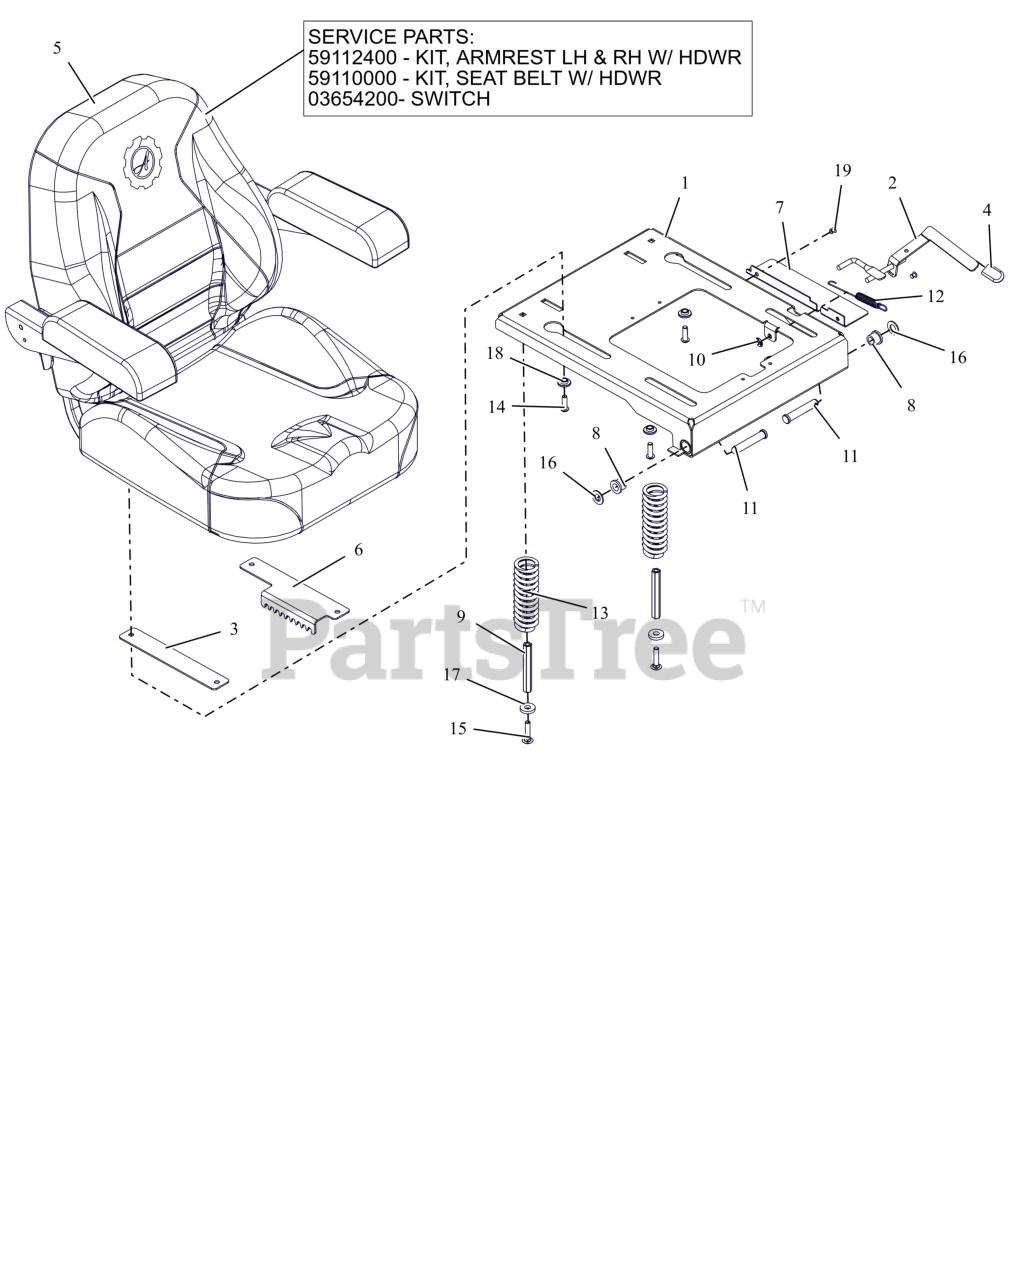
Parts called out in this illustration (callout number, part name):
1	WLDMT, SEAT PLATE HD
2	WLDMT, SEAT SLIDE LEVER
3	PLATE, ADJUSTABLE SEAT SLIDE
4	GRIP, SEAT LEVER, GREY
5	SEAT, APEX
5	KIT-LH & RH ARM REST-05124700
5	KIT-SEAT BELT REPLACE-05007300
5	SWITCH- SEAT
6	PLATE, HD SEAT ADJUSTMENT
7	GUARD, SEAT PLATE
8	BSHG, FLG .516X.750X.625X.937
9	NUT, COUPLING 5/16X18 X 3.75
10	NUT-PUSH .312
11	PIN-CLIC .50X2.70X2.31 -ZCC
12	SG-TENS .06X.482X5.35
13	SPRING, COMPRESSION SEAT 224LB
14	BLT,SHCS-BTN .31-18X1.00 ZCC
15	BLT,RHSN .31-18X1.50 G5 ZCC
16	WSHR, FLT .531X1.00X.063 ZCC
17	WSHR, FLT .406X1.00X.188 ZCC
18	BSHG-FLG .325X.499X.3X.875
19	RIVET, .1875 AL/AL .126-.250
